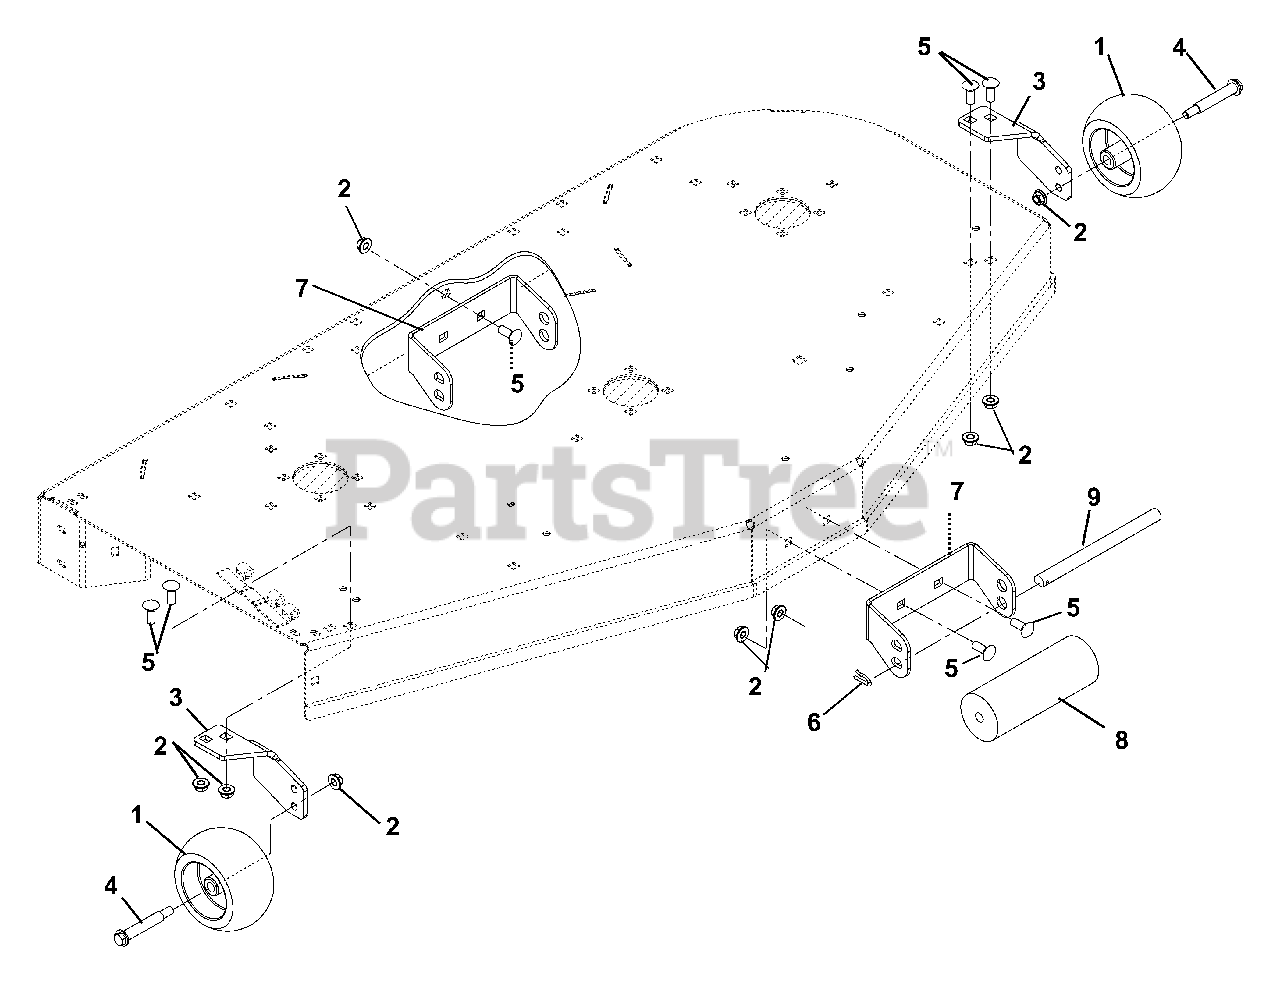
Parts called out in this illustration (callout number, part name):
1	Wheel, 5 x 3
2	Nut, 3/8-16 Flange Nyloc
3	Bracket, Anti Scalp
4	Bolt, Shoulder .38-16 x 2.50 Hex Washer Head Grade 5
5	Bolt, Round Head Square Neck .38-16 x 1.00 Grade 5
6	Pin, Spring Clip
7	Bracket, Roller Mount
9	Pin, Roller
